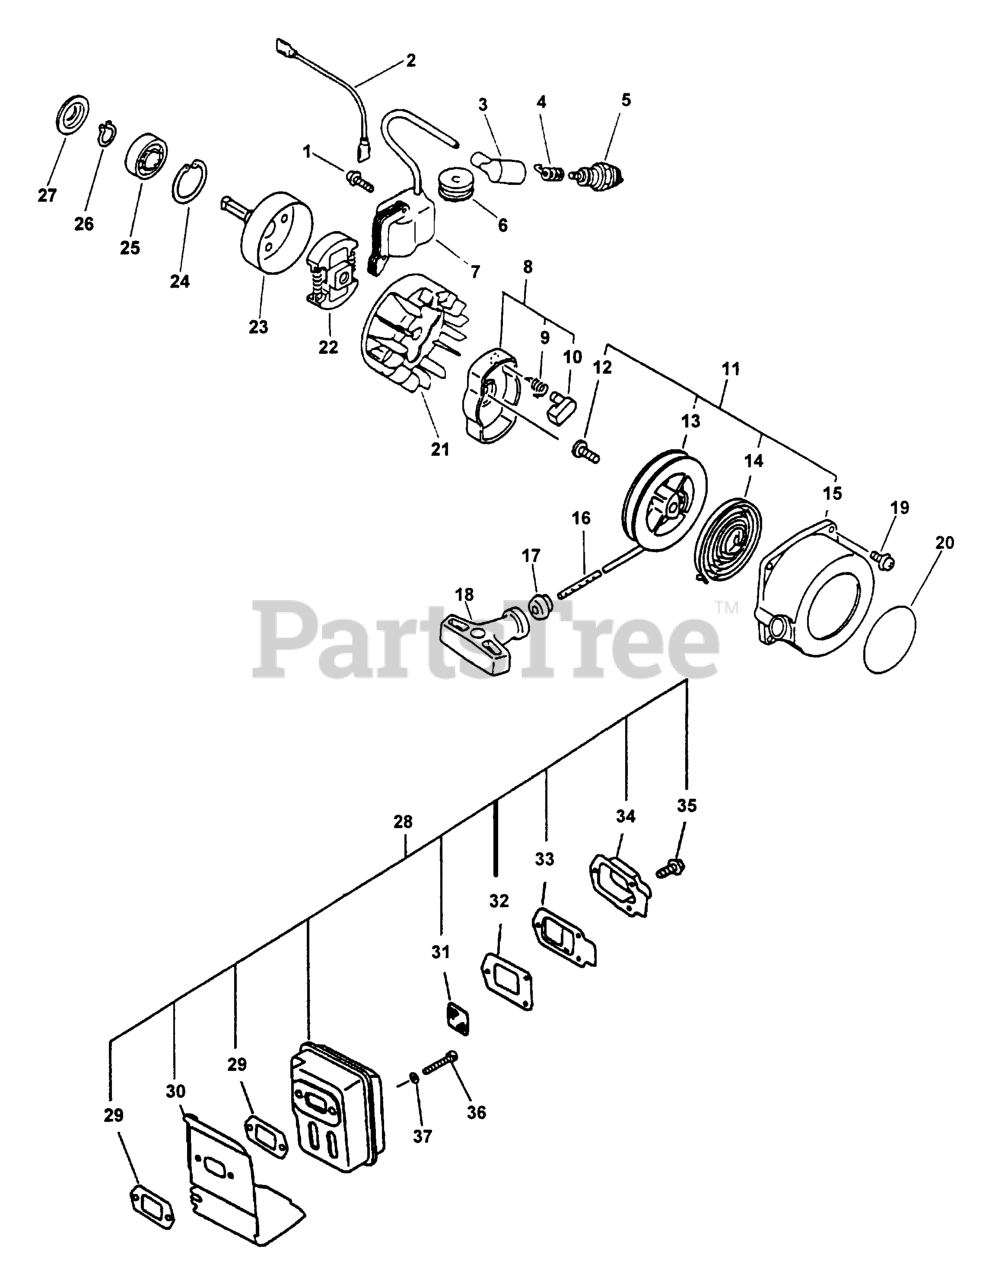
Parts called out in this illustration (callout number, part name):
1	SCREW 4x22
2	LEAD - GROUND
3	CAP, SPARK PLUG
4	TERMINAL, SPARK PLUG
5	SPARK PLUG - BPM-7Y
6	GROMMET
7	COIL, IGNITION
8	PAWL ASSY, STARTER
9	SPRING, RETURN
10	PAWL, STARTER - BLACK
11	STARTER ASSY, RECOIL
13	REEL, ROPE
14	SPRING, RECOIL
15	CASE, RECOIL STARTER
17	GUIDE, ROPE
18	GRIP, STARTER
19	BOLT 4x16
20	LABEL - BRAND
21	FLYWHEEL
22	CLUTCH ASSY
23	DRUM, CLUTCH
24	RING, SNAP 32
25	BEARING, BALL 6201-ZZ
26	RING, SNAP 12
27	STOPPER
28	MUFFLER ASSY
29	GASKET, EXHAUST
30	HEAT SHIELD, EXHAUST
31	SCREEN, SPARK ARRESTER
32	GASKET, EXHAUST
33	GUIDE, EXHAUST
34	GUIDE, EXHAUST
34	GUIDE, EXHAUST - INNER
35	SCREW 4x10
36	BOLT 5x55
37	WASHER, FLAT 5.5x10x0.8
